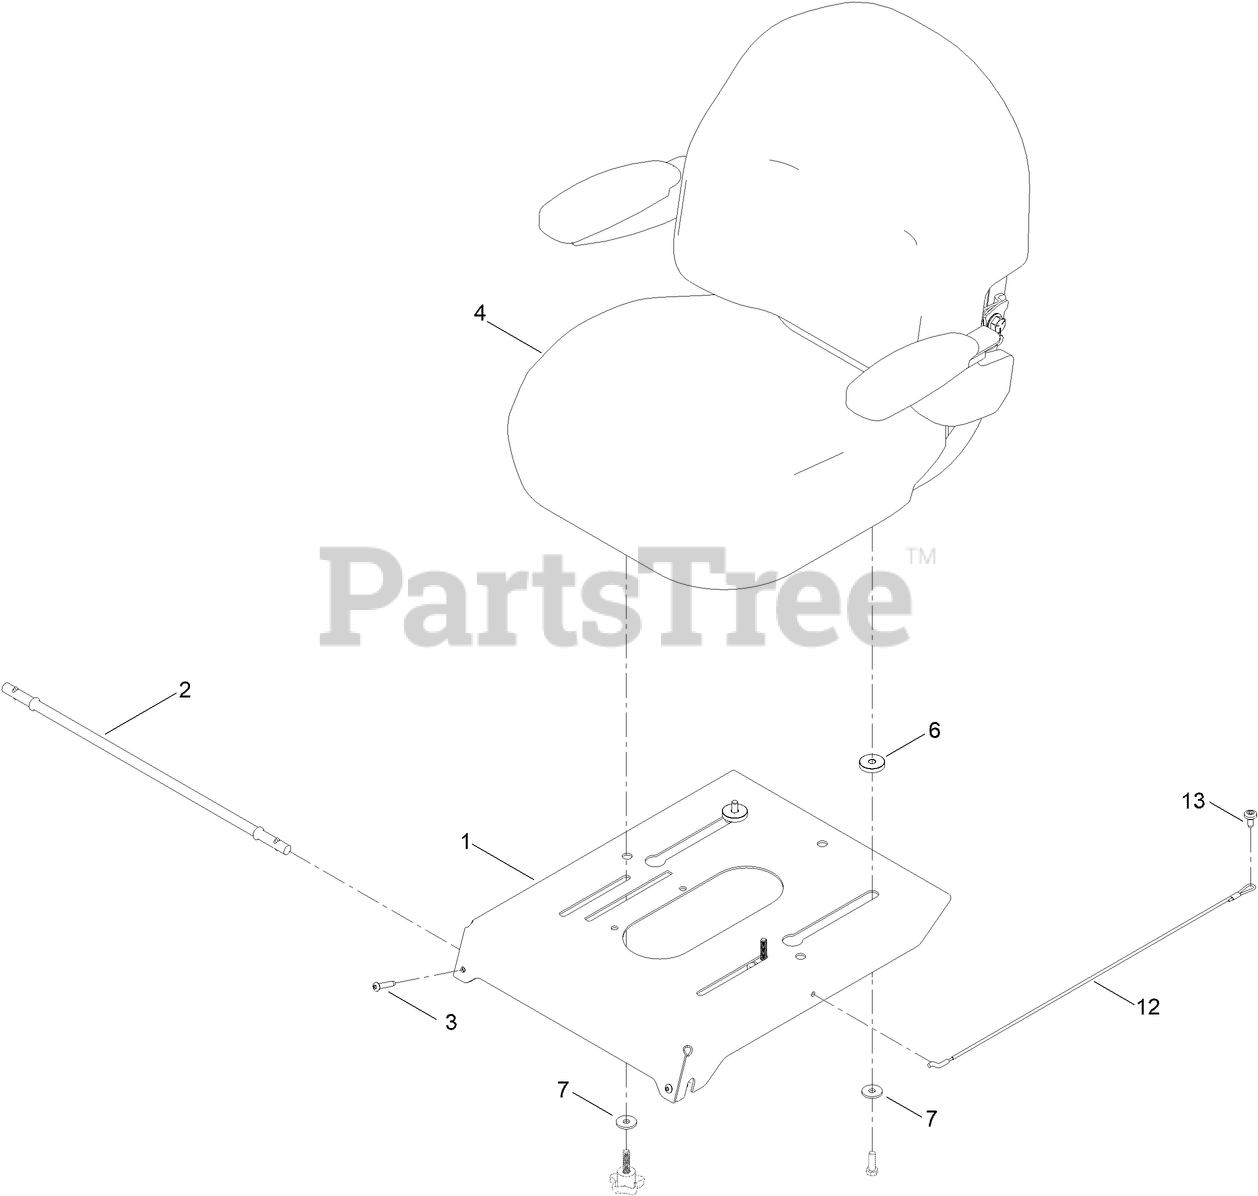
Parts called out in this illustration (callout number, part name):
1	PAN-SEAT, DELUXE
2	ROD-PIVOT
3	SCREW-TTH, THREAD ROLLING
4	SEAT ASM
6	SPACER-STEPPED
7	WASHER-FRICTION
12	CABLE-LANYARD
13	SCREW-SHOULDER
